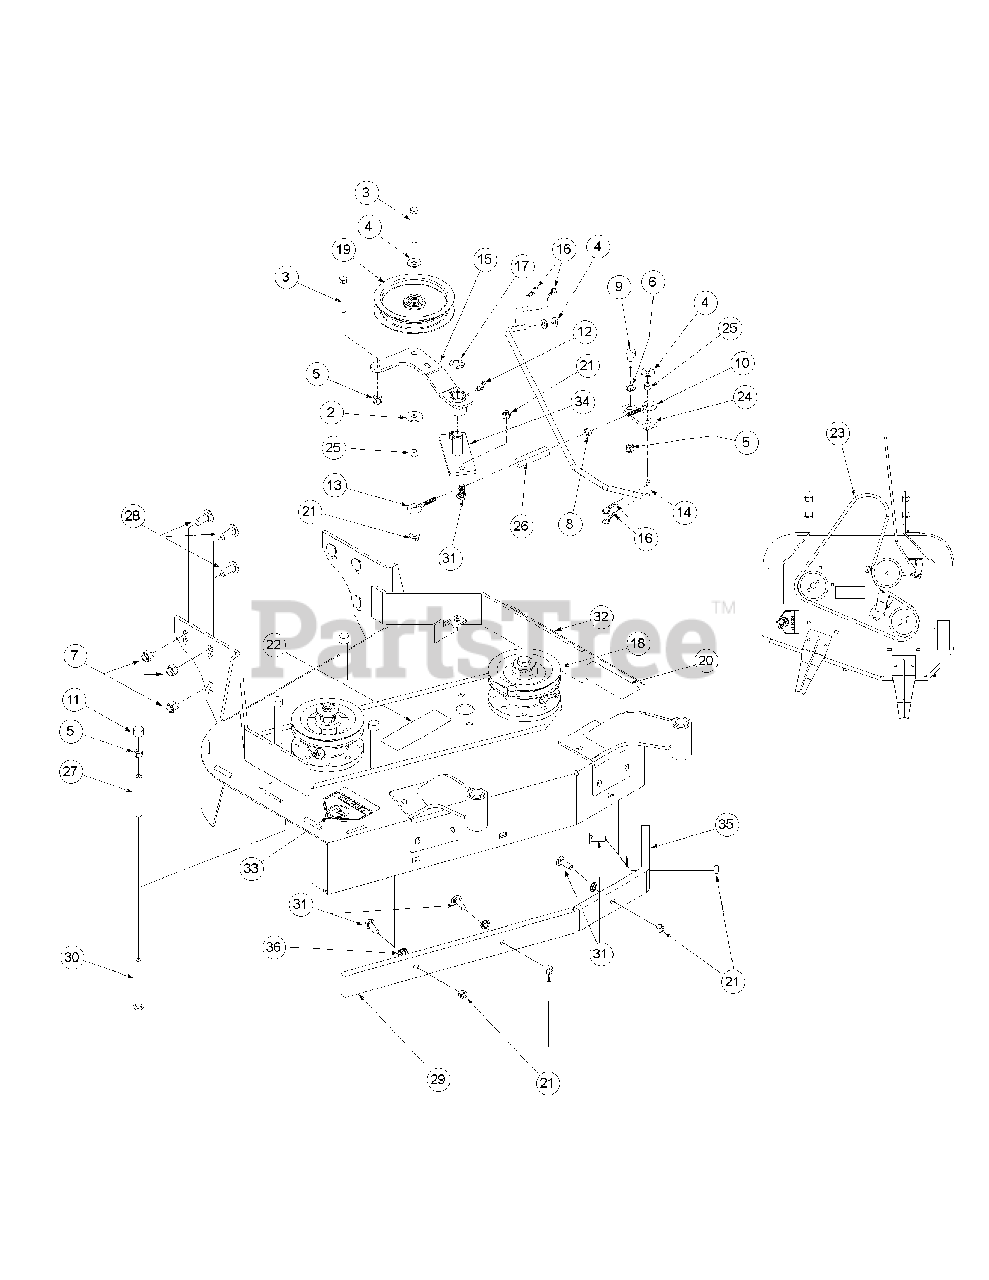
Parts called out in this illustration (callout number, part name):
1	Deck Stiffener
2	Washer, 1.25 x .411 x .100
3	Hex Cap Screw, 3/8-16 x 2.75
4	Flat Washer, 3/8 Zinc
5	Lock Nut, Nylon Insert, 3/8-16
6	Shim Washer
7	FlangeLock Nut, 1/2-13
8	Hex Nut, 5/16-18
9	Shoulder Bolt
10	Eye Bolt, Right Hand
11	Cap, Black Vinyl
12	Grease Fitting, 1/4-28 x 3/16
13	Eye Bolt, Left Hand
14	Blade Clutch, Rod
15	Idler Arm
16	Hair Pin, 3/8"-1/2"
17	E-Ring, Retainer
18	Deck Pulley
19	Idler Deck Take-up
20	Decal Rotating Blade
21	Hex Nut Flange Lock, 3/8-16
22	Decal, Warning Shield Missing
23	Belt Drive
25	Turnbuckle, Sleeve
26	Turnbuckle
27	Spacer, Belt Guide
28	Carriage Bolt, 1/2-13 x 1-1/4
29	Bumper, Deck 32"
30	Carriage Bolt, 3/8-16 x 4.5
31	Carriage Screw, 3/8-16 x 1.25
33	Decal, Danger, Hands and Feet
34	Idler Base
35	Bumper, Deck 32"
36	Push Retainer
